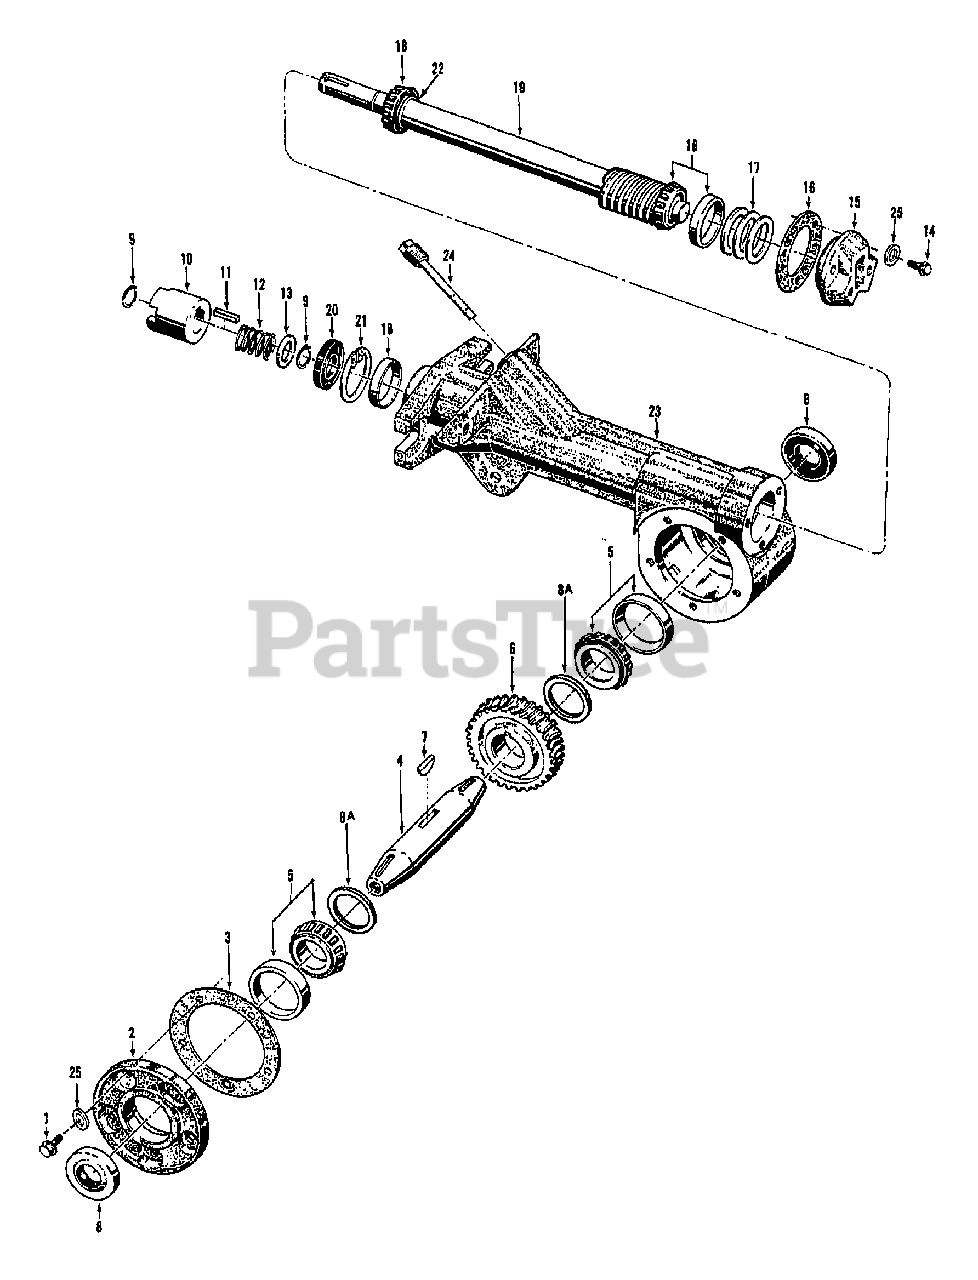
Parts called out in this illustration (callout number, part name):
1	SCR-HH 1/4-20X.625
3	GASKET-TILLER COVER
4	SHAFT-TILLER
5	KIT-BEARING CUP & CONE
6	GEAR-WORM MACH
7	KEY-WOODRUFF .250X1.01
8	SEAL-OIL TILLERSHAFT
8A	WASHER-1.75X1.260X.054
9	RING-RETAIN EXT .707 ID
10	KIT-CLUTCH DOGS TILLER
11	KEY-.188 SQX1.0
12	SPRING (TC)
13	SHIM-1.0X.7656X.062
14	SCR-HFLK 1/4-20X.875
15	COVER-REAR BRG BLACK
16	GASKET-BRG COVER
17	SHIM-1.75X1.5X.01
17	SHIM-1.75X1.5X.03
17	SHIM-1.75X1.5X.005
17	SHIM-1.75X1.5X.062
18	KIT-BRG CONE&RACE-DRIVESHAFT
19	KIT-TILLER DR SHAFT
20	SEAL-OIL DRIVESHAFT
21	RING-RETAINING 5000-181
22	SHIM-1.0X.7656X.062
23	HSG-TLR ATT W/SLEEVE/RACEH3
24	ASSM-OIL DIPSTICK
25	WASHER
